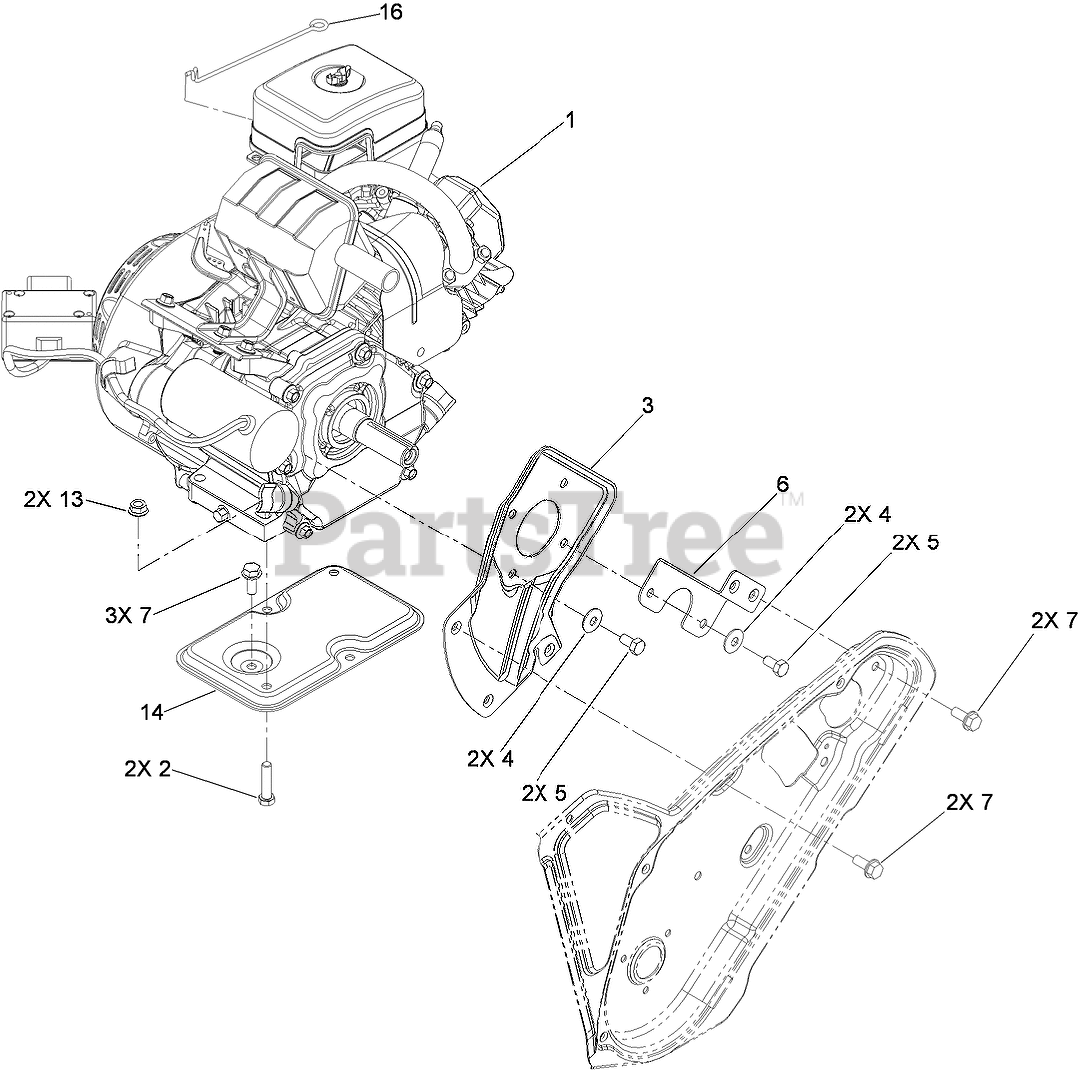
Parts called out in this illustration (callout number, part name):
1	ENGINE-LC168FDS-1
2	SCREW-HH
3	PLATE-ENGINE, PTO
4	WASHER-BELLEVILLE
5	SCREW-HH
6	SUPPORT-ENGINE, SIDE
7	SCREW-HWHTF
13	NUT-HF
14	SUPPORT-ENGINE
16	LINK-KNOB, CHOKE
